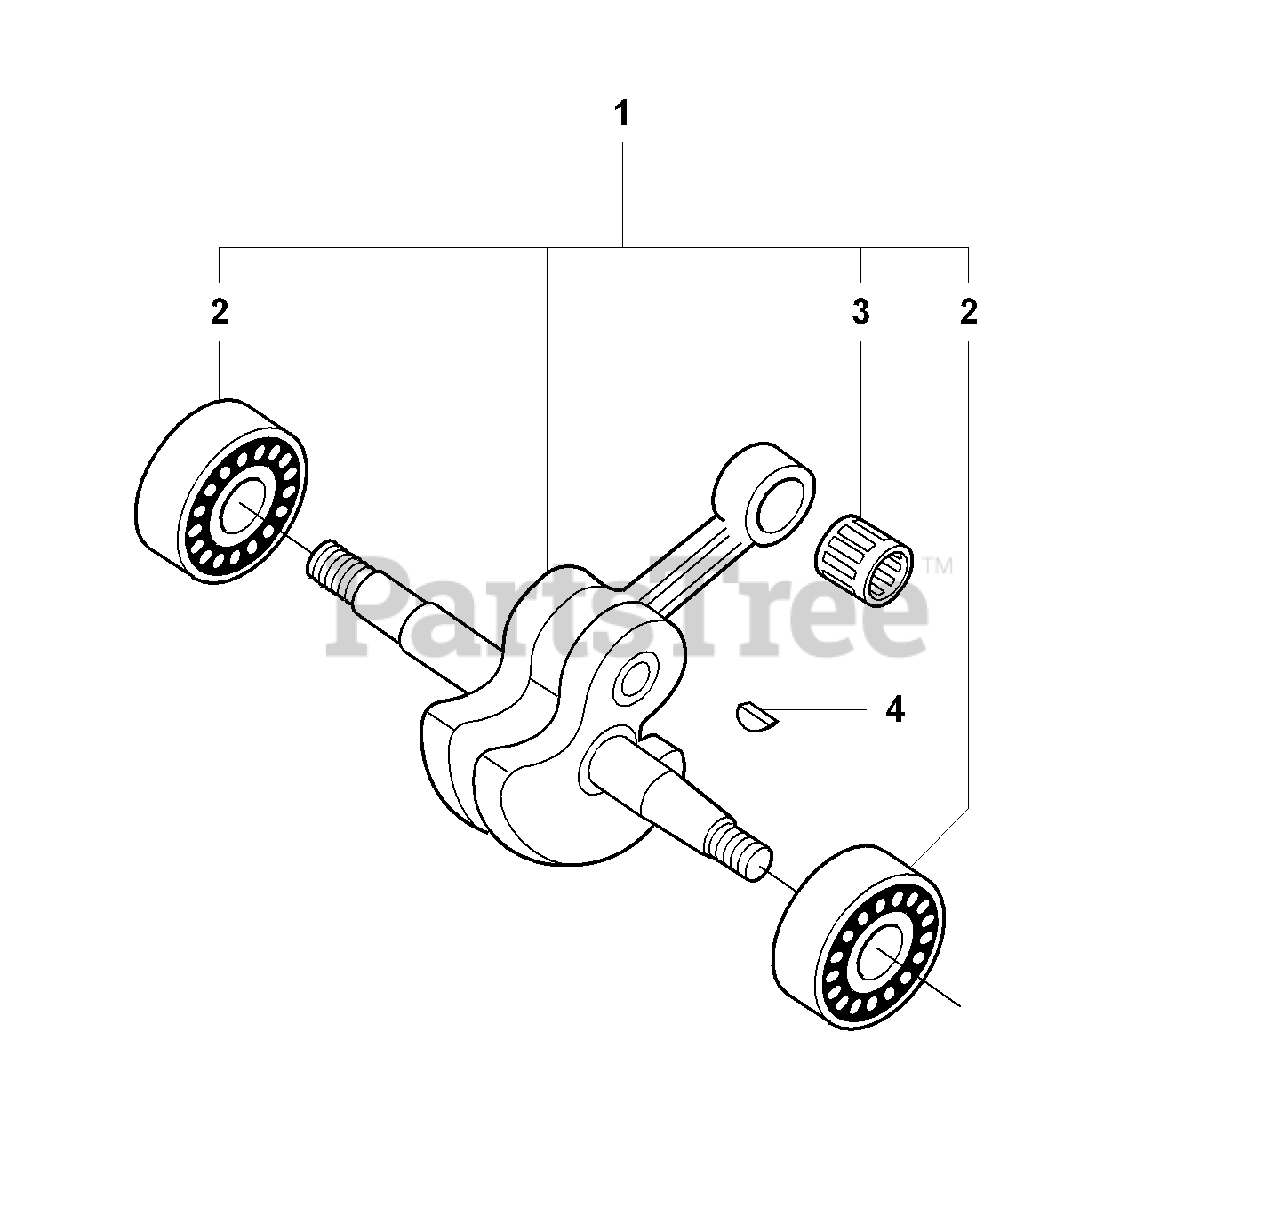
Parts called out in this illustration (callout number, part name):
1	CRANKSHAFT ASSY
2	BALL BEARING
3	SUPPORT BUSHING
4	WOODRUFF KEY
